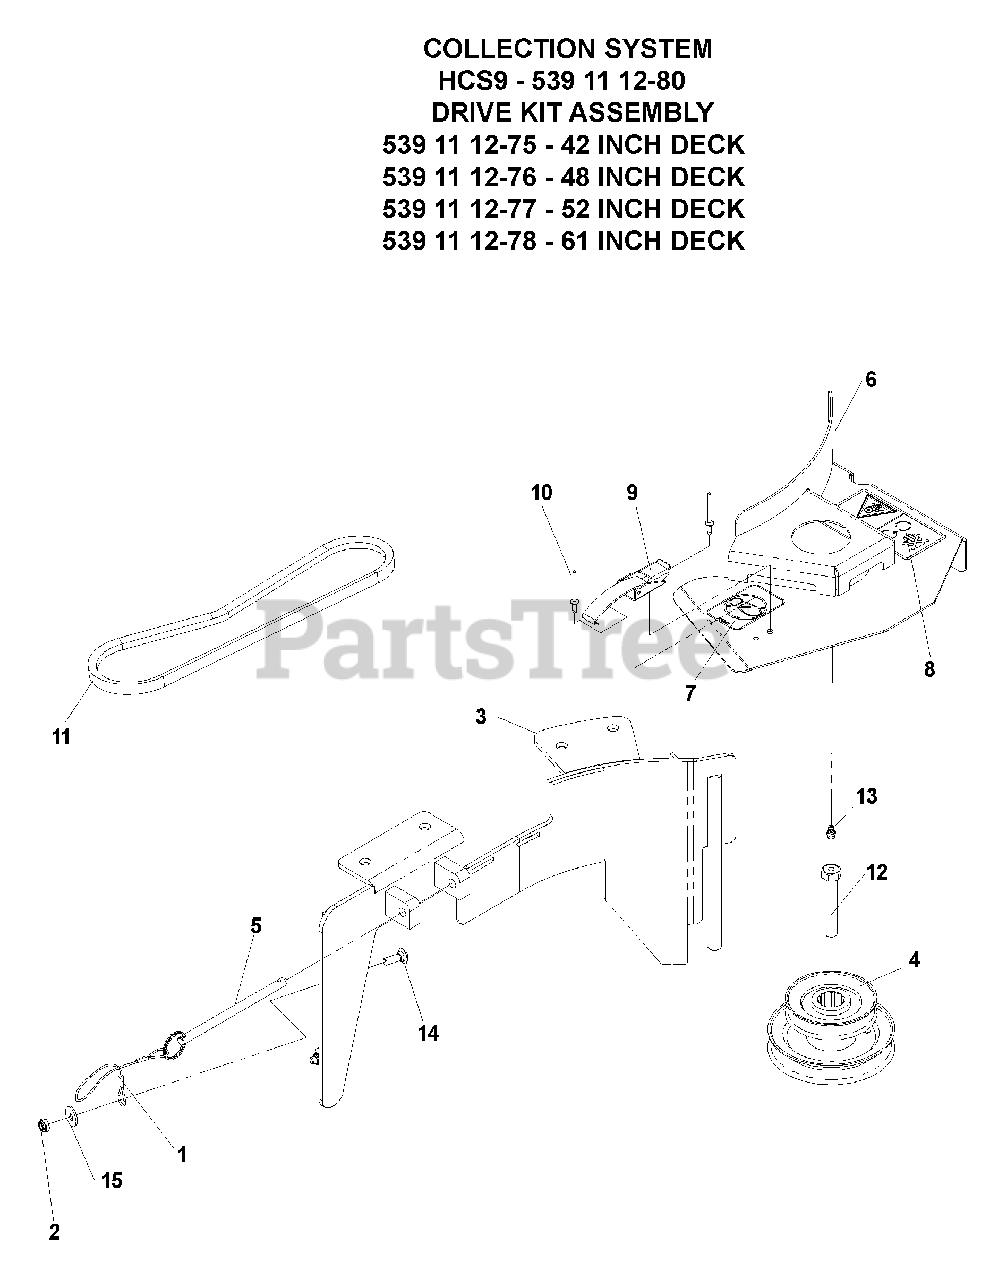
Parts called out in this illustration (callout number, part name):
2	NUT, 1/4-20, THIN NYLOC
3	BLOWER DECK PLATE, 42/48" DECKS
3	BLOWER DECK PLATE, 52" DECKS
3	BLOWER DECK PLATE, 61" DECKS
4	STACKED DOUBLE PULLEY, 42/48" DECKS
4	STACKED DOUBLE PULLEY, 52" DECKS
4	STACKED DOUBLE PULLEY, 61" DECKS
6	BELT SHIELD, 42" DECKS
6	BELT SHIELD, 48" DECKS
6	BELT SHIELD, 52" DECKS
6	BELT SHIELD, 61" DECKS
7	DECAL, EURO NO STEP
8	DECAL, EURO DANGER BELT
9	DRAW LATCH
11	BELT, 42" DECKS
11	BELT, 48" DECKS
11	BELT, 52" DECKS
11	BELT, 61" DECKS
12	HCS, 7/16-20 X 2 1/2, GR8
13	ZERK, STRAIGHT, 1/4-28
14	RHSNB, 1/4-20 X 3/4, GR2
15	WASHER, 1/4
539111275	42 INCH DECK
539111276	48 INCH DECK
539111277	52 INCH DECK
539111278	61 INCH DECK
539111280	Drive Kit Assembly Collection System
